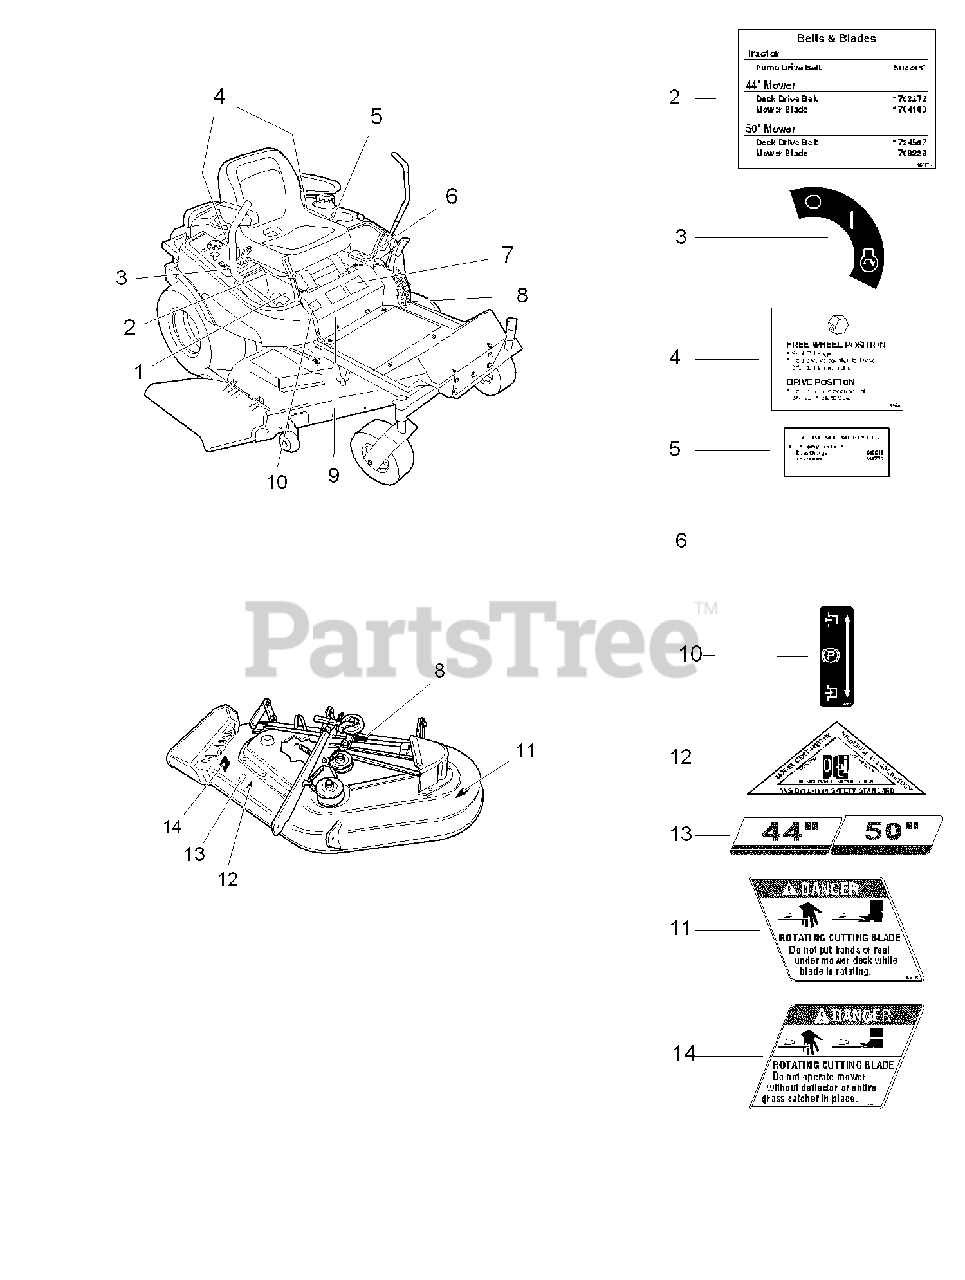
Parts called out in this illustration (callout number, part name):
1	DECAL, Motion Control, RH
2	DECAL, Belt and Blade
3	DECAL, Ignition Switch Symbol, White/Black
4	DECAL, Transmission Release, Free Wheel
5	DECAL, Touch Up Paint
6	DECAL, Motion Control, LH
7	DECAL, Danger
8	DECAL, I.D. Plate
9	DECAL, Warning
10	DECAL, Parking Brake
11	DECAL, Danger Do Not Put Hands/Feet in Mower
12	DECAL, OPEI Certified
13	DECAL, 44"
13	DECAL, 50"
14	DECAL, Danger Do Not Operate Without Deflector
